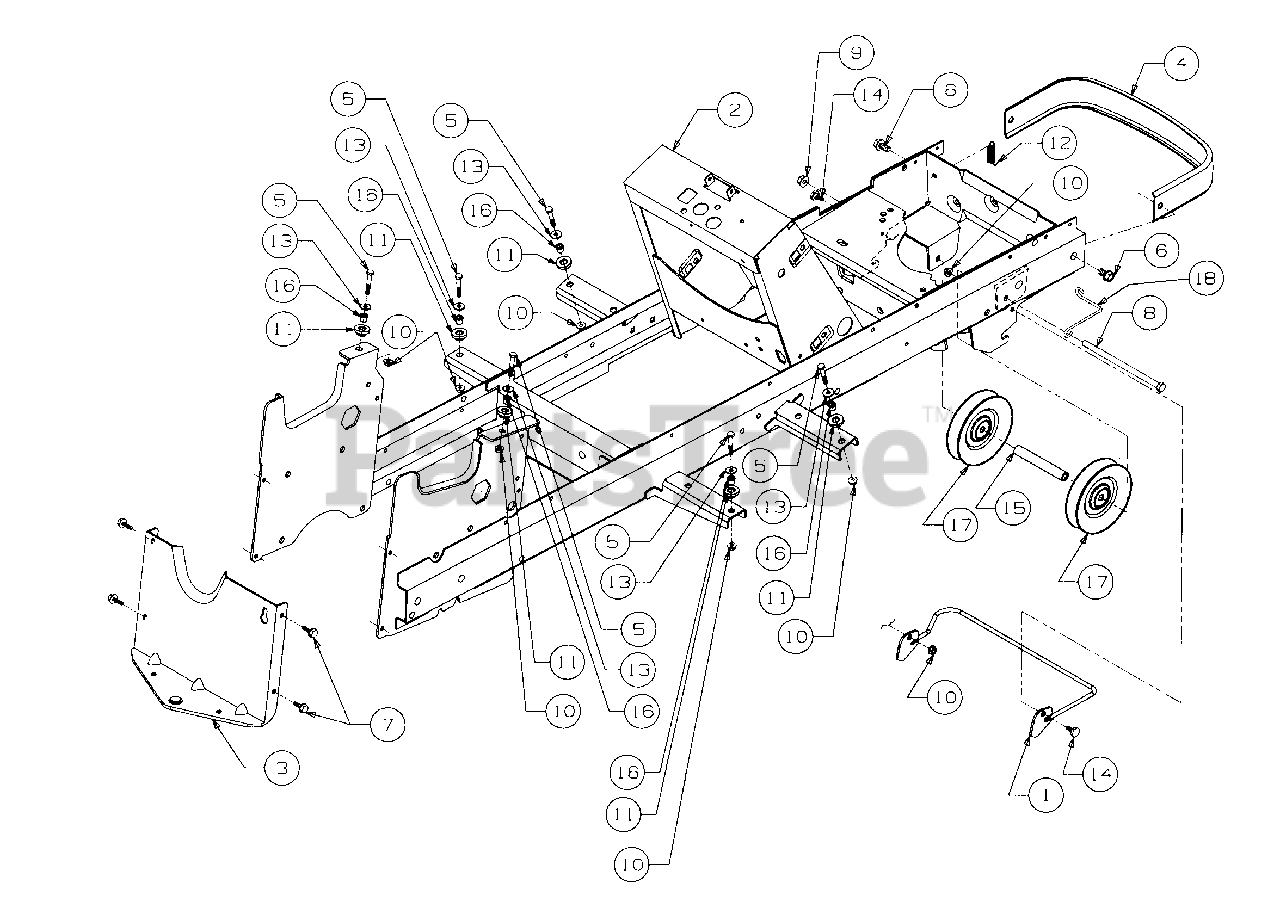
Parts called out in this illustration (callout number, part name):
1	Rod, Quick Attach
4	Bumper
5	Screw, Hex Cap, 1/4-20 x 1.0
6	Screw, Hex Wsh Hd Tapp 3/8-16 x .75
7	Screw, Hex Wsh Hd Tap 5/16-18 x .75
8	Screw, Hex Cap, 3/8-16 x 7.0
9	Nut, Hex Flange Lock, 3/8-16
10	Nut, Hex Flange Lock, 1/4-20
11	Grommet, Insulator
12	Spring, Latch
13	Washer, Flat, .255 x .72 x .60
14	Bolt, Shoulder
15	Spacer, Idler, .407 x .720 x 4.38
16	Spacer, .28 x .40 x .42 Lg
17	Pulley, Idler
18	Belt Guide
